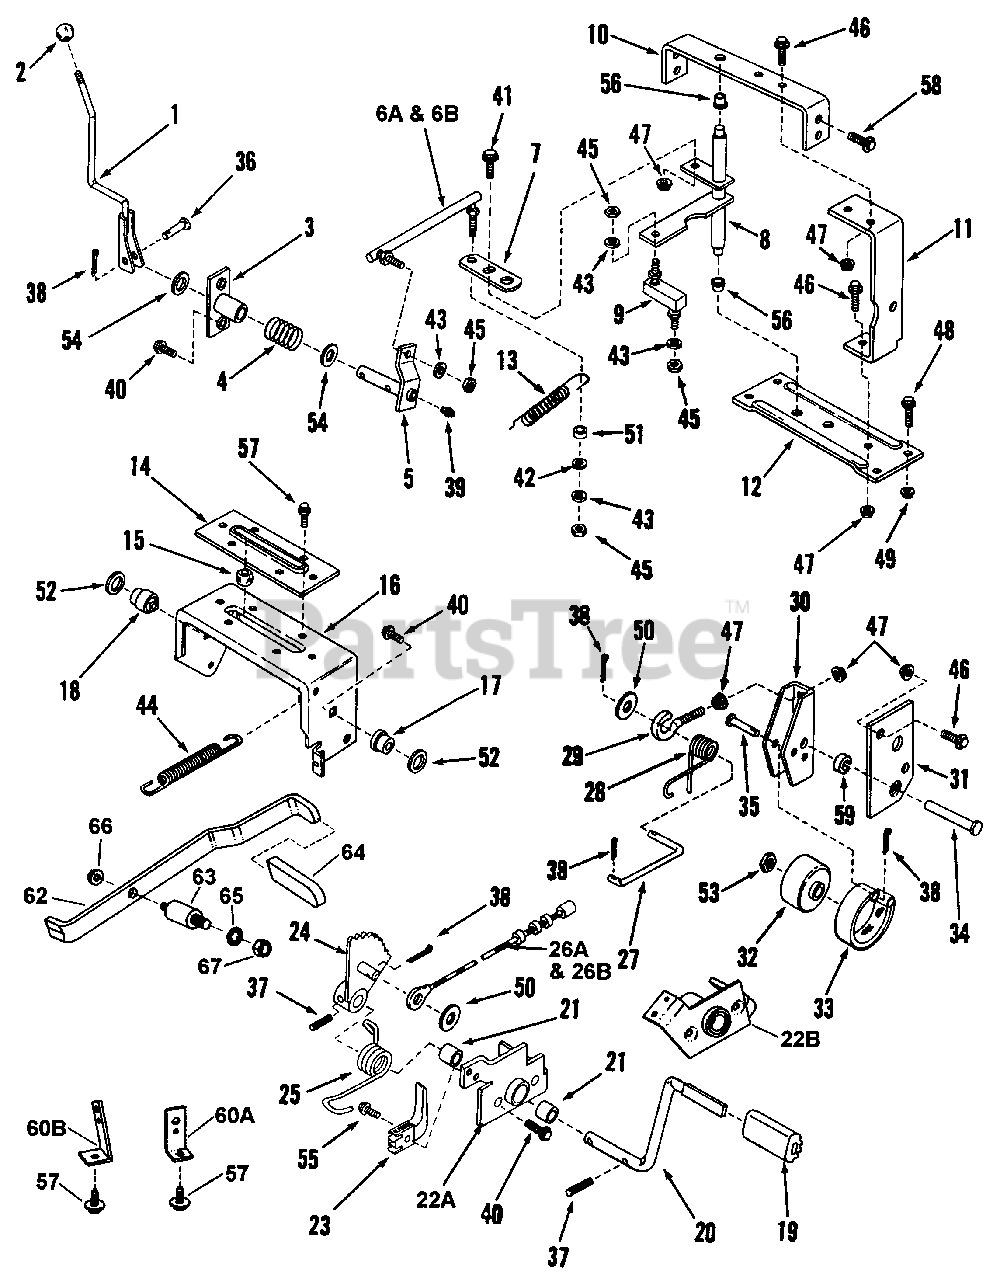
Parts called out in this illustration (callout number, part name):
1	SHIFTER, Transmission
2	KNOB, Shifter
3	PIVOT, Shift
4	SPRING, Shift Detent
5	ARM, Shifter
6A	LINK, Shift-Long (8.53")(84)(No longer available)
6B	LINK, Shift-Long (9.53")('85)
7	ARM, Shift Adjusting
8	ARM, Shift
9	LINK, Shift-Short
10	STRAP, Upper Cross
11	STRAP, Brake Pivot Support (No longer available)
12	STRAP, Lower Cross (No longer available)
13	SPRING, Reverse Assist
14	RETAINER (PLATE), Clutch Yoke Bushing
15	BUSHING, Clutch Ball
16	YOKE, Clutch
17	BUSHING, Yoke Pivot-Short
18	BUSHING, Yoke Pivot-Long
19	PAD, Pedal
20	PEDAL, Clutch Brake
21	BEARING, Sleeve
22A	BRACKET, Pedal Pivot
22B	BRACKET, Pedal Pivot
23	SWITCH, Clutch Interlock
24	ARM, Clutch/Brake
25	SPRING, Clutch/Brake
26A	CABLE, Clutch/Brake, 27.62", 1984
26B	CABLE, Clutch/Brake, 36.0", 1985
27	LINK, Brake
28	SPRING, Torsion
29	EYE-BOLT, 5/16-18 x 2"
30	LEVER, Brake Pivot
31	SUPPORT, Brake Pivot
32	DRUM, Brake
33	BAND, Brake
34	PIN, 3/8 x 2-9/16" Clevis
35	PIN, 1/4 x 1-13/16" Clevis
36	PIN, 3/8 x 1-1/4" Clevis
37	PIN, 3/16" x 1-1/4" Roll
38	PIN, 3/32 x 3/4" Cotter
39	FITTING, Lube
40	SCREW, 5/16-18 x 5/8" Hex Flange Self-Tap
41	BOLT, 5/16-18 x 5/8" Hex Flange Lock
42	WASHER, 5/16 SAE
43	WASHER, 5/16 Split Lock
44	SPRING
45	NUT, 5/16-24 Hex
46	BOLT, 5/16-18 x 3/4" Hex Flange Lock.
47	NUT, 5/16-18 Hex Flange Lock, Grade 5
48	BOLT, 3/8-16 x 3/4" Hex Flange Lock
49	NUT, 3/8-16 Hex Flange Lock
50	WASHER, 3/8 SAE Flat
51	ROLLER, Shift Arm
52	WASHER, Shim
53	JAM-NUT, 5/8-18
54	WASHER, Thrust
55	SCREW, #10-24 x 1" Self-Tap
56	BEARING, Nylon
57	SCREW, 1/4-20 x 1/2" Hex Flange Self-Tap
58	SCREW, 3/8-16 Hex Flange Self-Tap
59	RING
60A	CLIP, Spring Attach (R/B 7032446)
60B	CLIP, Spring Attach
61	KIT, Yoke Spring Tension (NLA)(See #'s 57 & 60)
62	LEVER, Parking Brake
63	STUD, Parking Brake
64	SLEEVE, Parking Brake
65	WASHER, 3/8 Internal Tooth Lock
66	NUT, 1/4-20 Small Flange
67	NUT, 3/8-16 Hex, Grade 5
